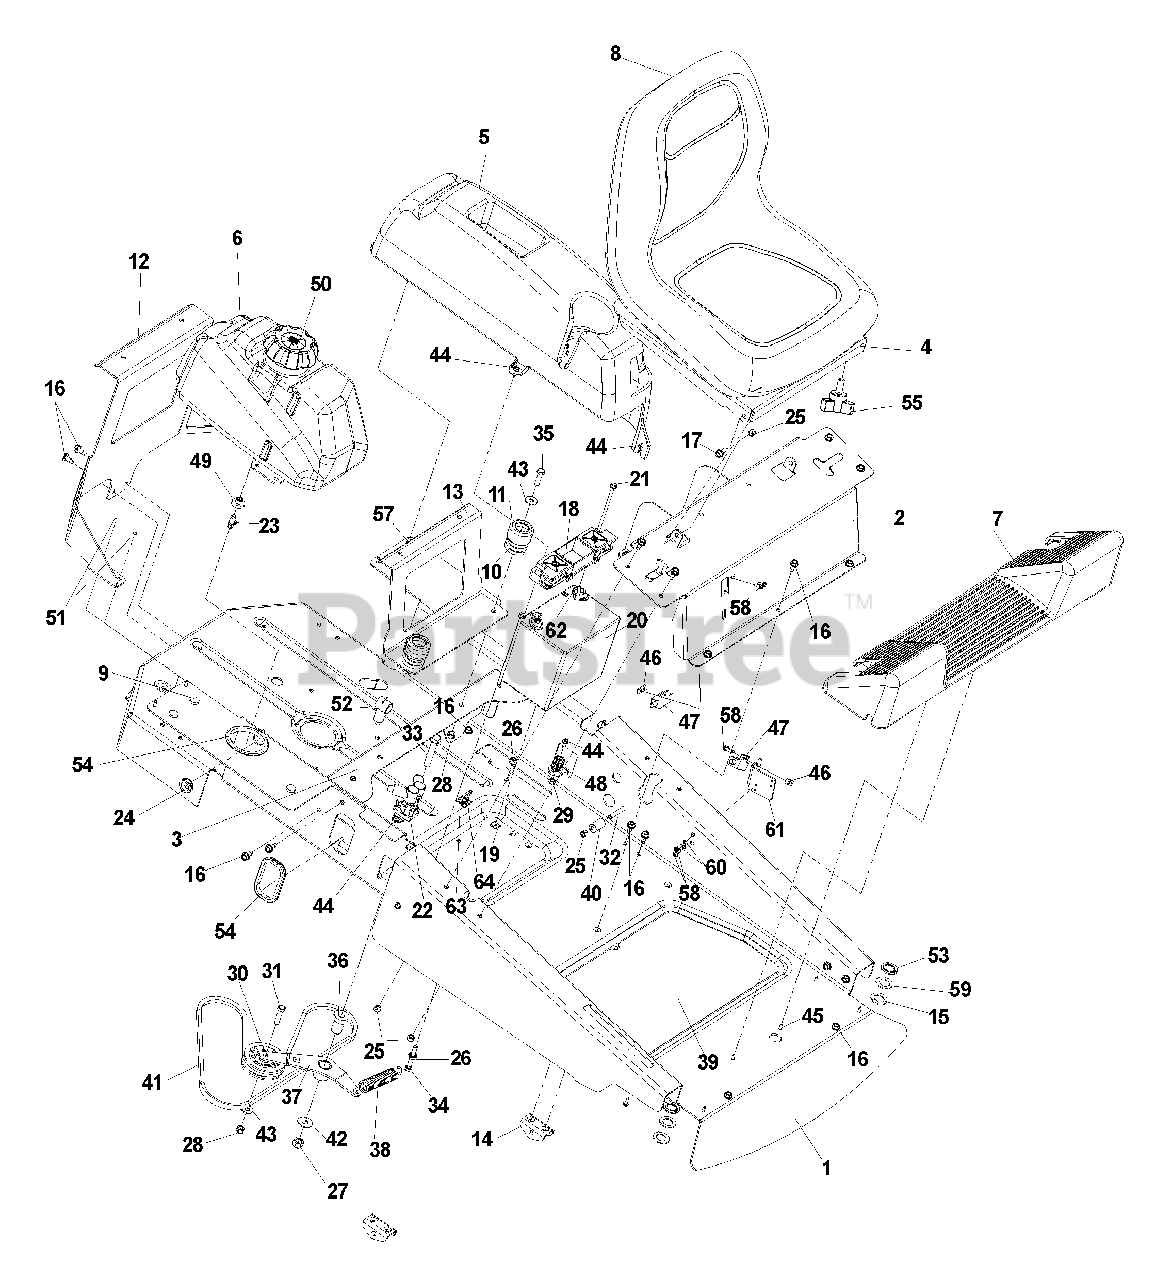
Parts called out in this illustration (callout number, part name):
1	FRAME, CHASSIS
2	CONSOLE
3	REAR SEAT SUPPORT
4	SEAT PLATE
5	FENDER, LEFT
6	TANK, FUEL
8	SEAT
9	RUBBER STOP
10	SPRING, SEAT
11	CAP, SPRING COVER
12	REAR BRACKET W/ DECALS, TOOLBOX
13	FRONT BRACKET, TOOLBOX
14	BRACKET, DECK HANGER
15	MACHINE BUSHING, 7/8
16	BOLT, 5/16-18 X 3/4, THREAD FORMING
17	BOLT, 5/16, SHOULDER
18	BATTERY HOLD DOWN
19	PUSH NUT, NYLON
20	BATTERY 12V
21	BOLT, 1/4 X 7 1/2
23	ELBOW, TANK
24	GROMMET, FUEL LINE
25	NUT, 5/16, NYLOC
26	NUT, 5/16C
27	NUT, 1/2C, NYLOC
28	NUT, 3/8C, CENTER LOCK
29	NUT, 1/4C, NYLOC
30	IDLER PULLEY, HYDRO'S
31	HCS, 3/8-16 X 1 1/2,
32	HCS, 5/16-18 X 2,
33	HCS, 1/2-13 X 2 3/4,
34	HCS, 5/16-18 X 2 1/4,
35	HCS, 3/8-16 X 1 1/4,
36	IDLER SPINDLE
37	IDLER ARM, PUMP
38	TRACTION SPRING
39	NON-SLIP MATTING
40	MOTION LIMITER
41	BELT, HYDRO
42	WASHER, 1/2
43	WASHER, 3/8
44	SCREW, 1/4C X 5/8, SELF TAPPING
45	SCREW, 10-24 X 5/8, WASHER HEAD
46	PLATE, SWITCH, THREAD FORM
47	SWITCH N C
48	SPRING, NEUTRAL RETURN
49	GROMMET, RUBBER
50	FUEL CAP
51	SCREW, 5/16 X 1, TAPTITE
53	RETAINING RING
55	KNOB W/STUD
57	SCREW, 10-12 X 1 1/4
58	SCREW, 10-24 X 5/8 SPEC
59	WAVE WASHER
60	LOCKWASHER, #10
62	HCS, 5/16-18 X 3/4
64	MOUNTING BLOCK, CABLE TIE
